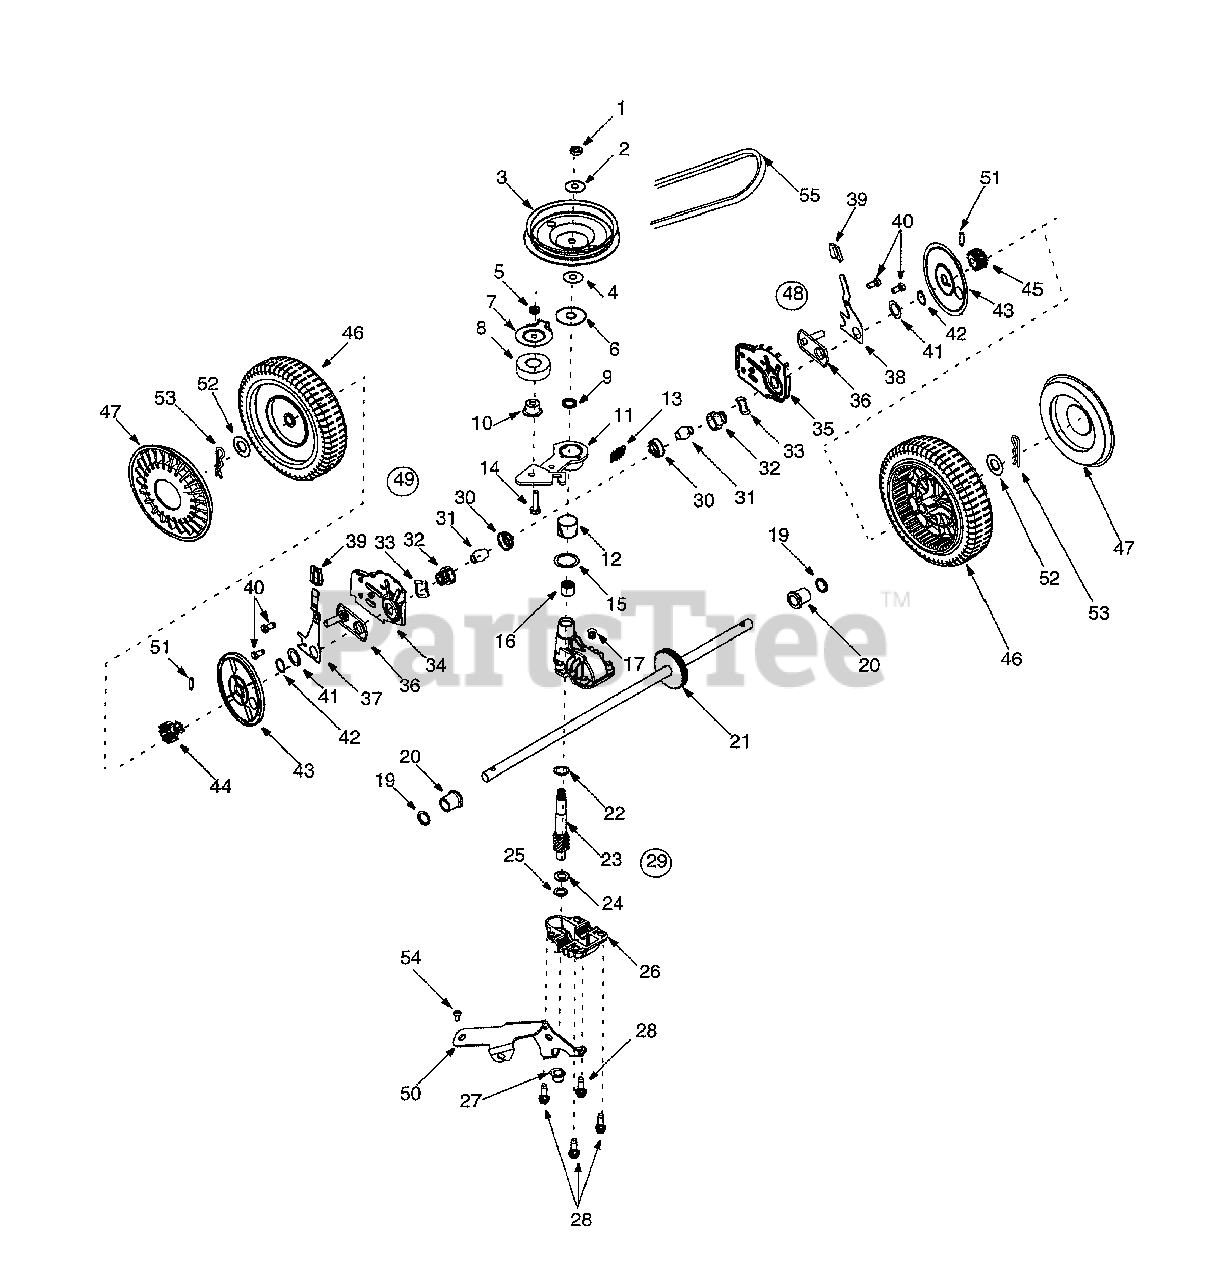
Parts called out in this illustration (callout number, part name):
1	Hex Jam Nut 5/16-24
2	Bell Washer .325 x .930 x .045
3	Pulley, 3.82 x .313 x .68
4	Bell Washer .325 x .930 x .045
5	Lock Nut 1/4-28
6	Flat Washer .442 x 1.38 x .060
7	Belt Keeper
8	Ball Bearing
9	Oil Seal
10	Flange Spacer
11	Idler Bracket Assembly
12	Bearing Sleeve
13	Extension Spring
14	Hex Cap Screw 1/4-28 x 1.00
15	Flat Washer .865 x 1.145 x .030
16	Needle Bearing .438 x .625 x .500
17	Plug 1/4 x .437
19	Oil Seal .500 x .687 x .094
20	Flange Bearing
21	Output Shaft
22	Flat Washer .504 x .700 x .030
23	Pinion Shaft 10T
24	Thrust Washer .375 x .70 x .030
25	Thrust Washer .388 x .625 x .062
26	Lower Housing
27	Flange Bearing .378 x .531 x .370
28	Hex Screw w/Washer 1/4-20 x .750
29	Transmission Assembly
30	Bearing Retainer
31	Bearing Sleeve .50 I.D.
32	Bearing Support
33	Wave Washer 1.5 x 1.0 x .029
37	RH Front Lever
38	LH Front Lever
39	Knob
40	Hex Cap Screw 3/8-16 x .75
41	Washer DD 1.5" O.D.
42	Snap Ring 1.0 dia.
43	Wheel Dust Cap
44	Gear 14T RH FWD
45	Gear 14T LH FWD
46	Wheel, 8x2 Black
47	Hubcap: Yellow
48	RH Height Adj.
49	LH Height Adj.
50	Cable Idler Bracket
51	Dowel Pin
52	Flat Washer 1/2 x 1.00 x .063
53	Cotter Pin .08 x 1.42
54	Screw
55	Belt
